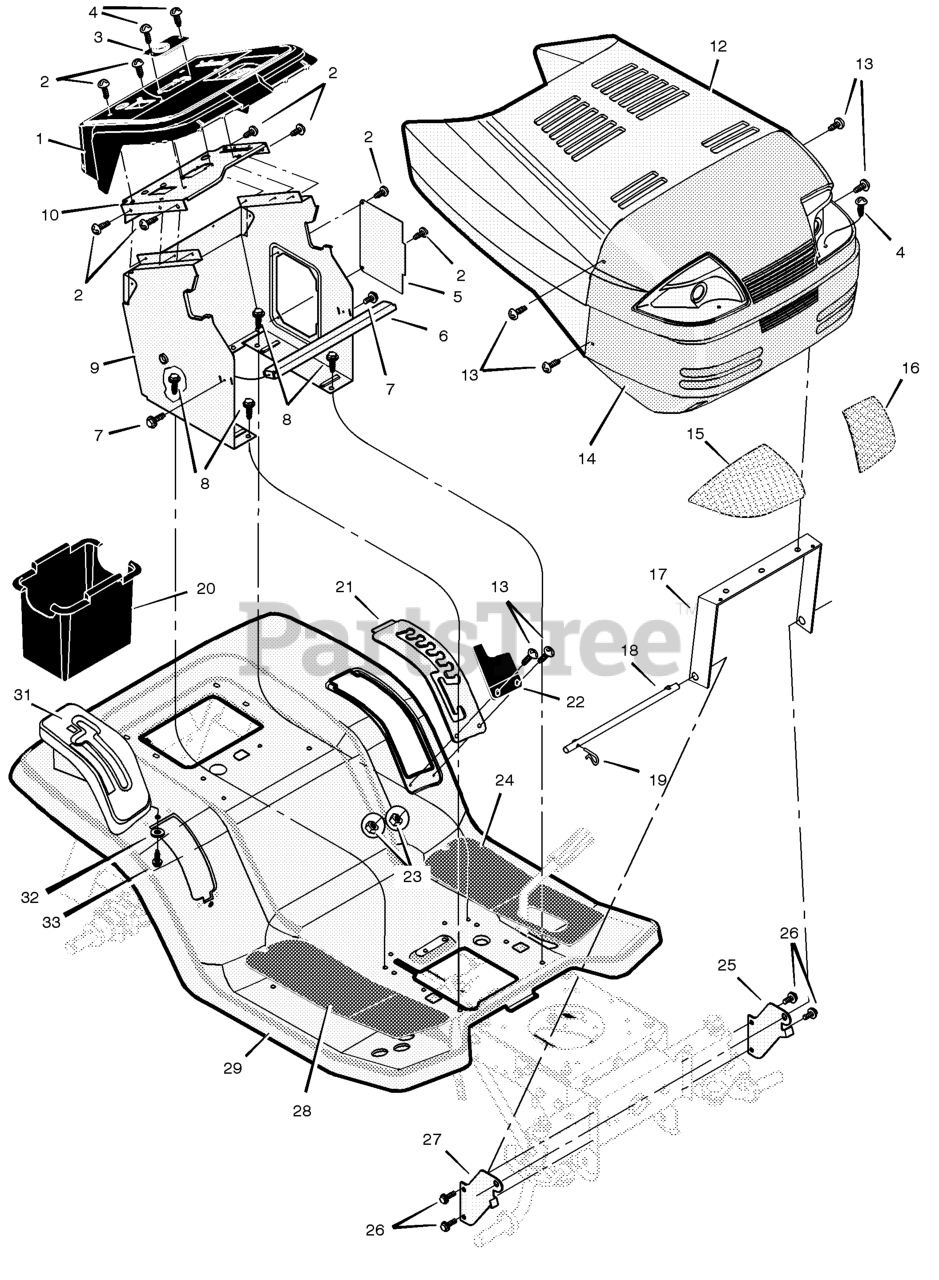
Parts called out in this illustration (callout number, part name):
2	Screw
3	Bearing, Upper Steering
5	Panel, Side Access
6	Channel, Support
9	Support, Dash
10	Plate, Dash
12	Hood
13	Bolt, Shoulder
14	Grille
15	Lens, Right
16	Lens, Left
17	Brace, Grille
18	Rod, Pivot
19	Pin, Hair
20	Container, Battery
21	Plate, Lift Detent
24	Mat, Left
25	Support, Left Grille
27	Support, Right Grille
28	Mat, Right
29	Deck, Seat
31	Cover, Shift
